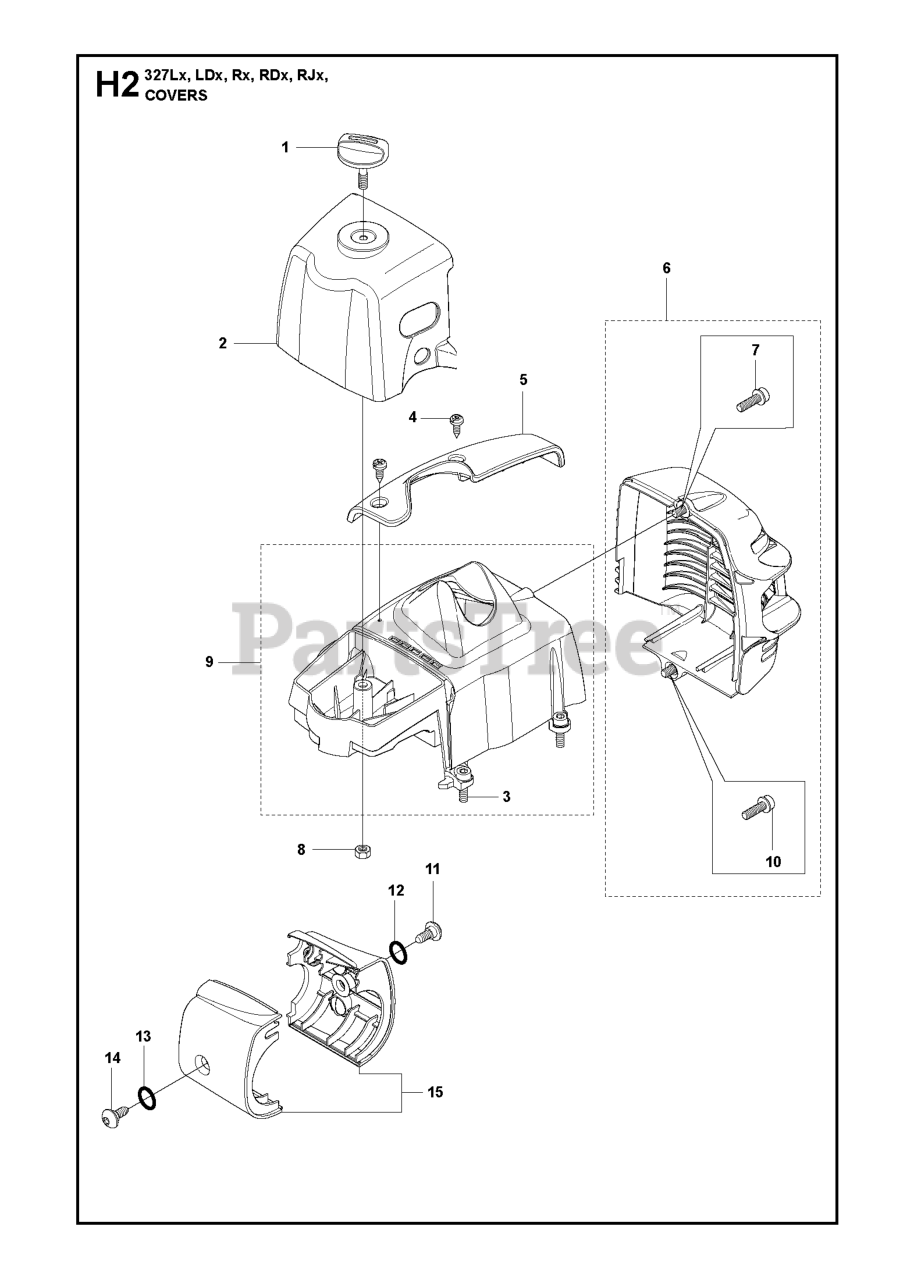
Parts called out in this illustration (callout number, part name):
2	FILTER COVER
3	SCREW IHSCFMO
5	ARM PROTECTION
6	HEAT PROTECTOR
7	SCREW IHSCFTO
9	CYLINDER COVER ASSY
10	SCREW IHSCFMO
11	SCREW MT5X11
12	O-RING 8X1.6
13	O-RING 8X1.6
14	SCREW MT5X11
